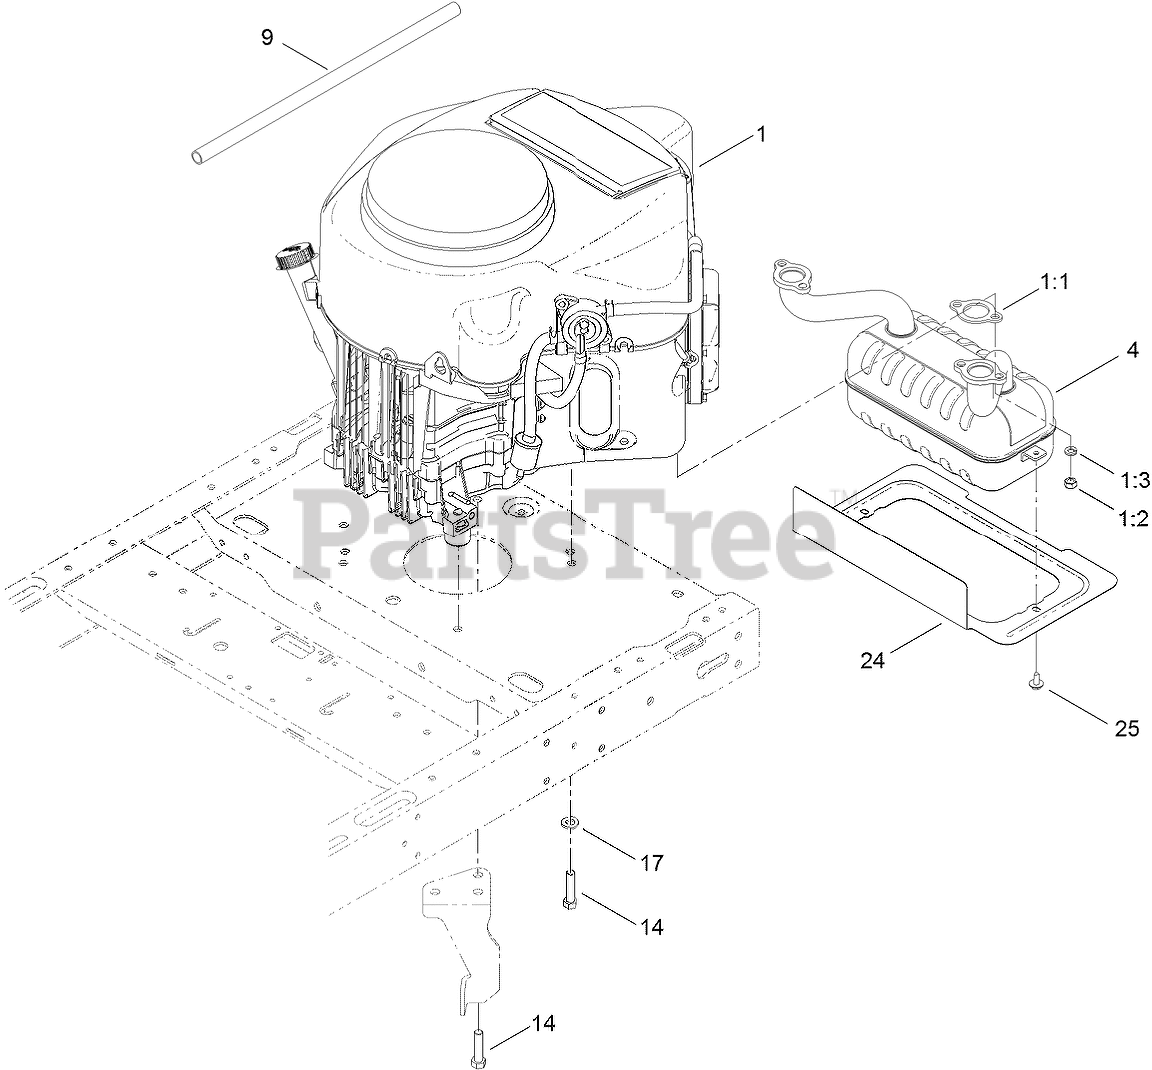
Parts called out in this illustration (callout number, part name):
1:1	GASKET-EXHAUST
1:3	WASHER-LOCK
4	MUFFLER-KAWASAKI
9	Hose-Oil Drain
14	BOLT-HH
17	WASHER-FLAT
24	SHIELD-HEAT
25	SCREW-HHFTF
